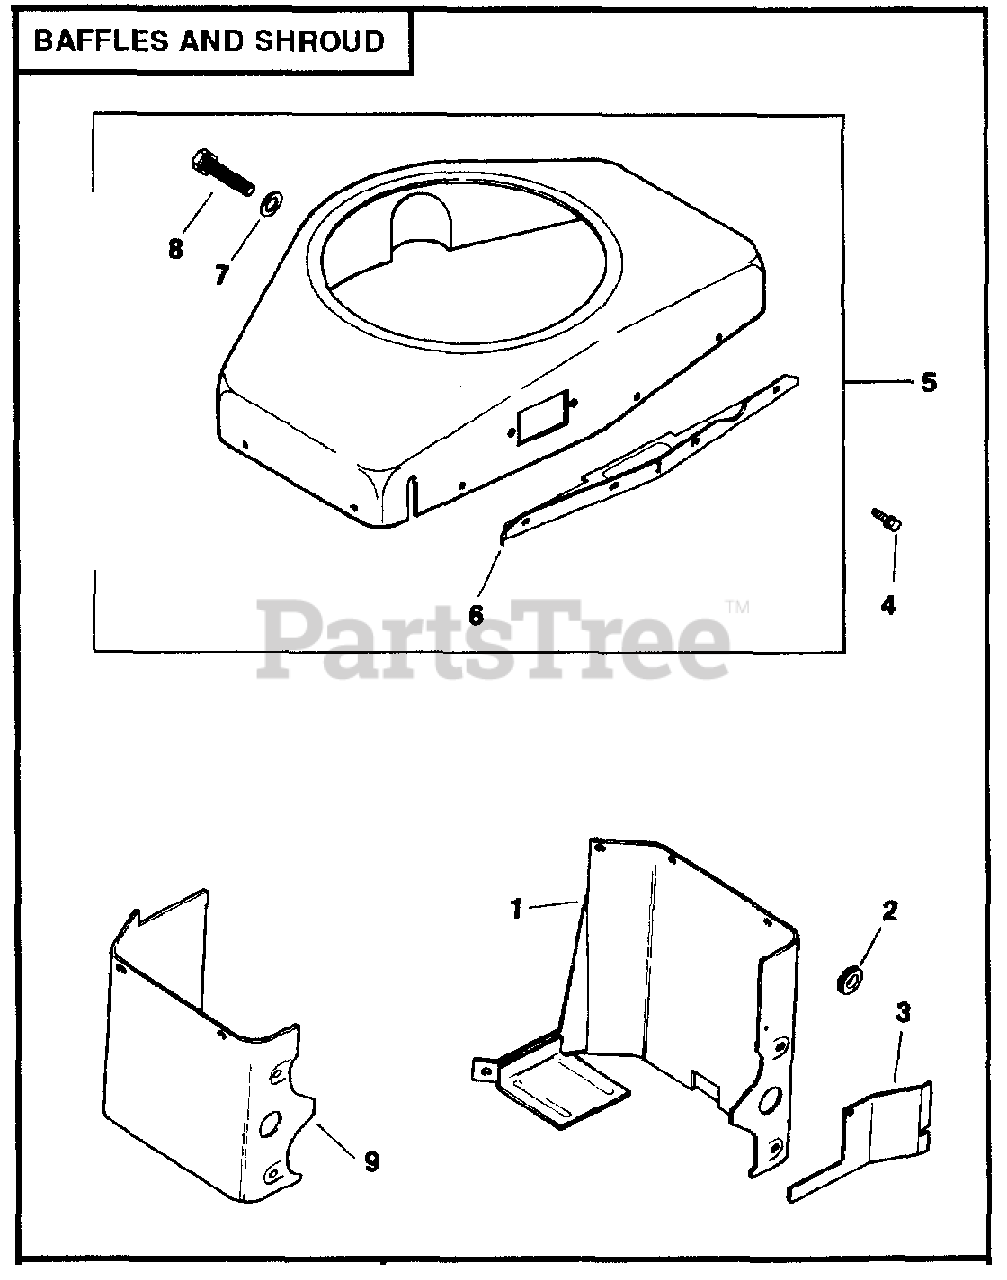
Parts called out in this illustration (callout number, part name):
1	BAFFEL, #2 HEAD
3	BAFFLE, FUEL PUMP
4	SCREW
9	BAFFLE, #1 HEAD
